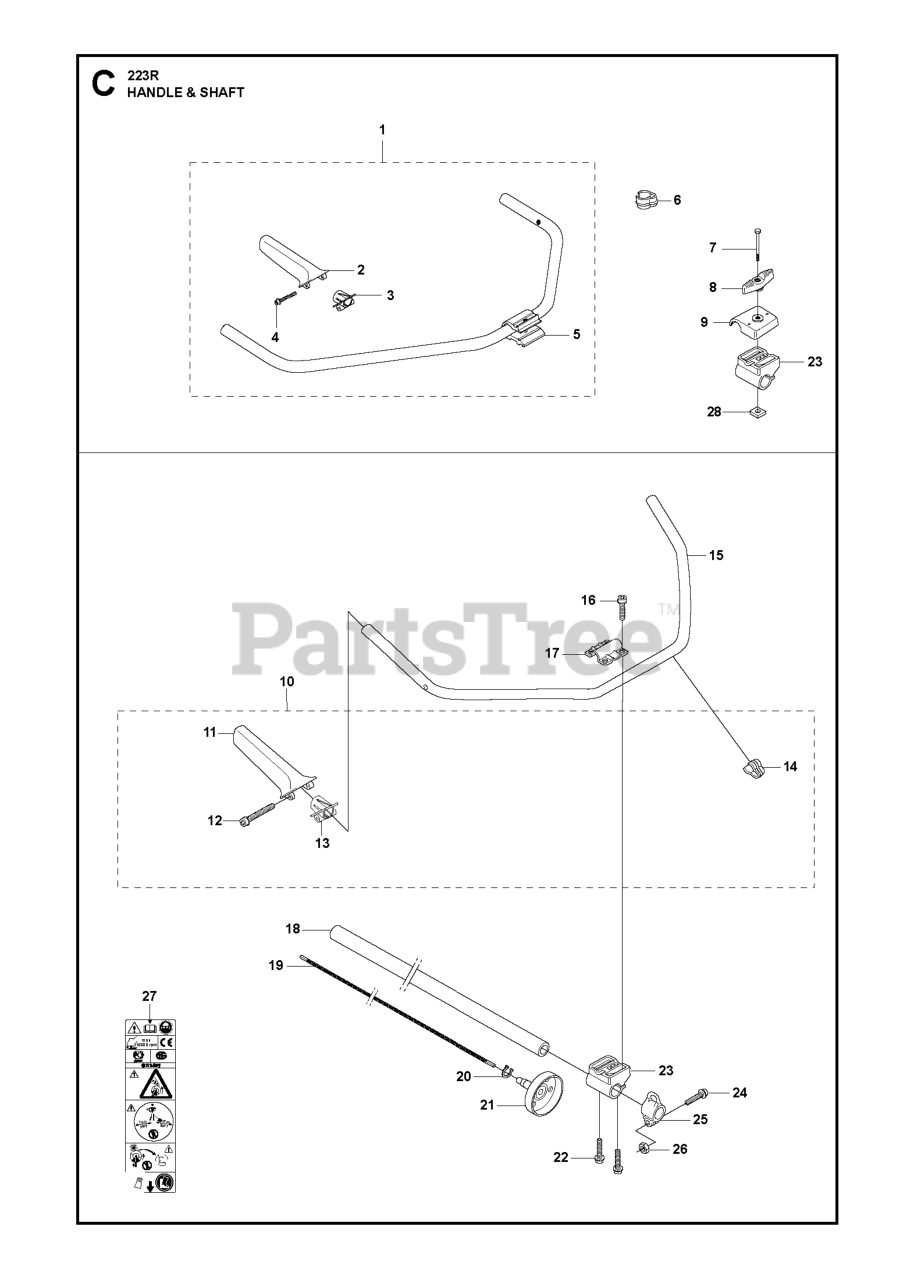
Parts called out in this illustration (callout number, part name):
5	HOLDER
18	SHAFT CPL
19	DRIVE SHAFT FLEX
20	RETAINING RING SGA 10
21	CLUTCH DRUM
24	SCREW
25	HARNESS HOLDER
27	LABEL WARNING TRIMMERS AND BRU
